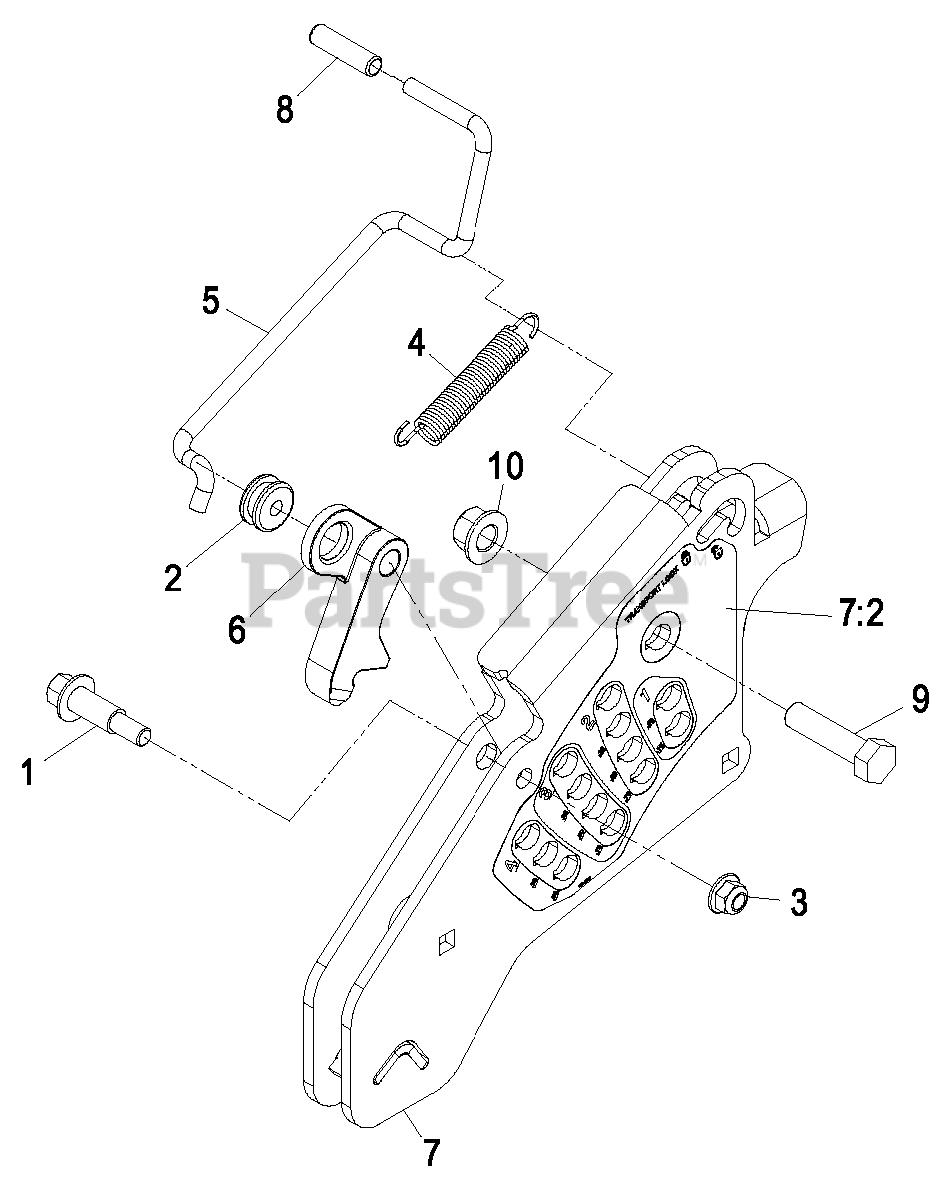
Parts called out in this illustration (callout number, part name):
1	BOLT-SHOULDER
2	GROMMET
3	NUT-HF, NI
4	SPRING-EXTENSION
5	ROD-LOCK, TRANSPORT
6	PAWL-TRANSPORT, HOC
7	HOC PLATE ASM
7:2	DECAL-HOC
8	GRIP-LEVER
9	SCREW-HH
10	Nut-Lock 1/2-13
